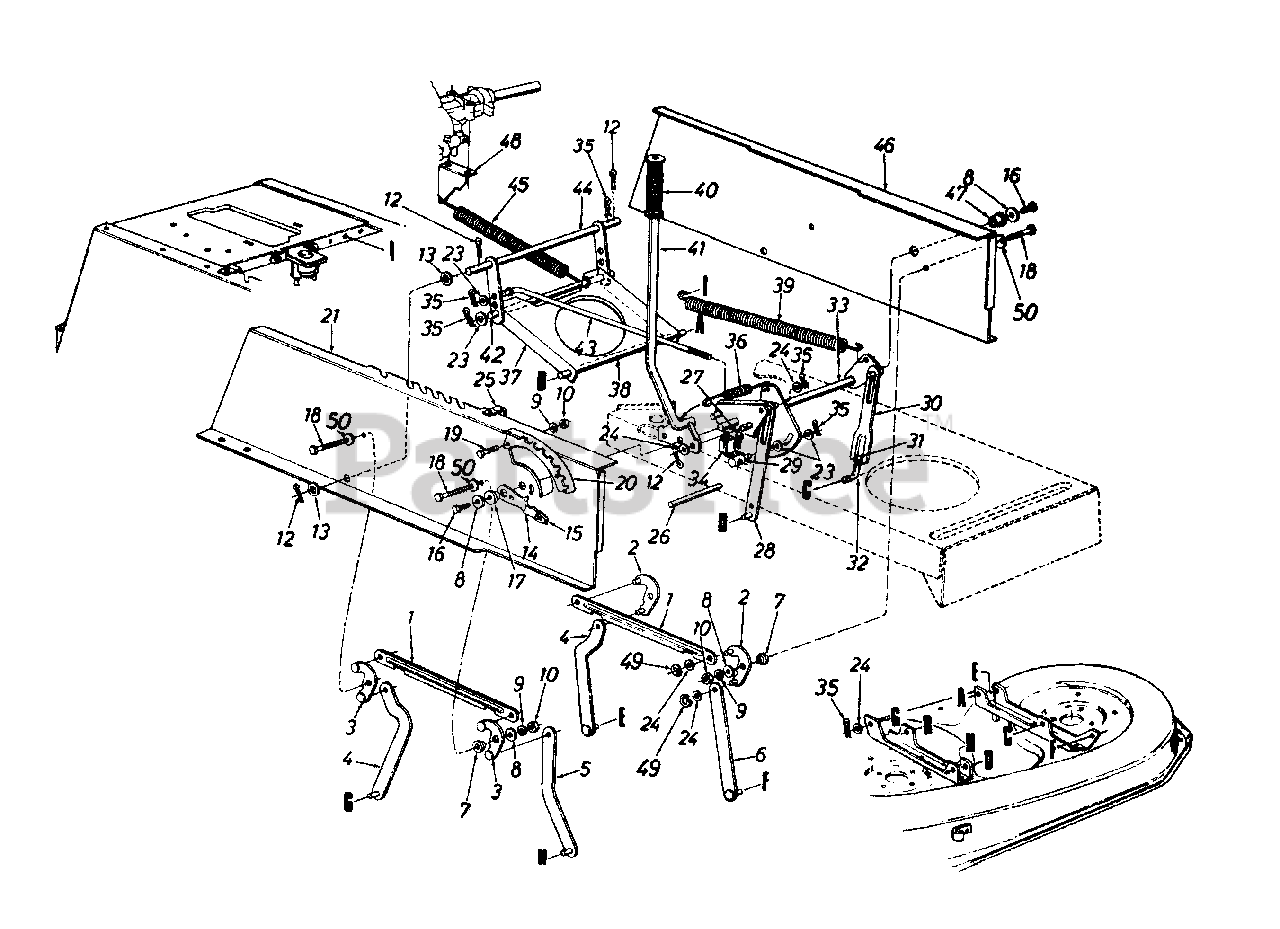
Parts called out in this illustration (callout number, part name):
3	Pivot Link Ass'y,--R.H.
7	Shld, Spacer .318" I.D.
8	Fl-Wash. .344" I.D. x .62" O.D.
9	L-Wash. 5/16" I.D.
10	Hex Nut 5/16-18 Thd. (Gr. 5)
12	Cotter Pin 1/8" Dia.
13	Fl-Wash. .635" I.D. x 1.0" O.D.
14	Height Adj. Stop Lever Ass'y.
15	Knob
16	Hex Wash. TT-Tap Scr. 5/16-18 x .75" Lg.
17	Flange Brg. .63" I.D.
18	Hex Wash. Hd. Scr, 5/16-18x .875" Lg.
20	Index Brkt.
24	Fl-Wash. .531" I.D. x .93" O.D.
25	Clamp
26	Running Board Rod
27	Hex Wash. Hd. Tap Scr.
31	Hex Nut 1/2-20 Thd. (Gr. 5)
32	Lift Link Adjuster
35	Inter, Cotter Pin 3/8" Dia.
36	Extension Spring
39	Extension Spring
40	Grip (Lift Handle)
43	Disengagement Rod
49	"E"-Ring
50	Bell-Wash. .325" I.D.
